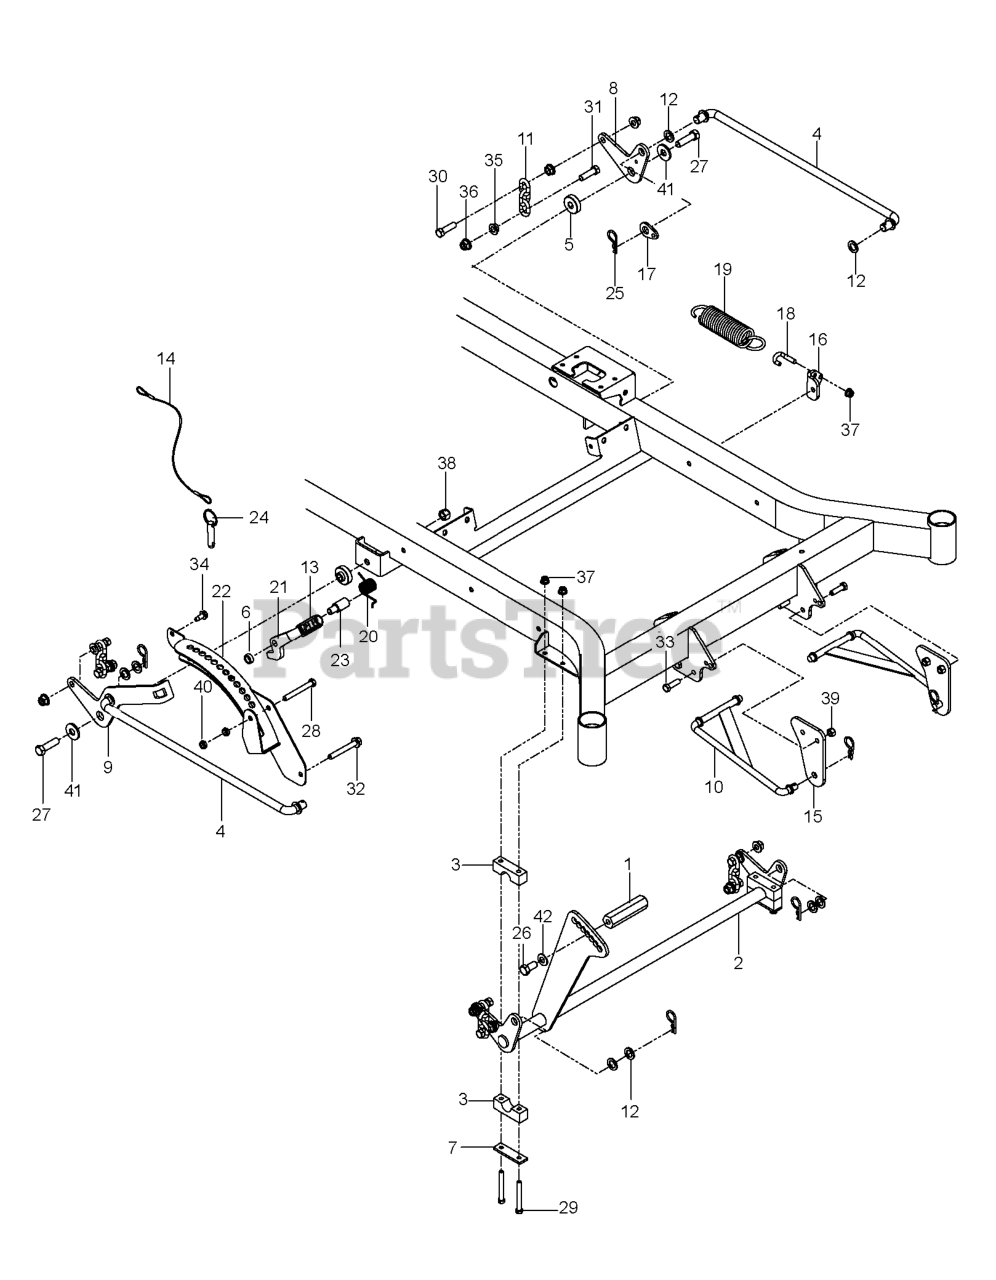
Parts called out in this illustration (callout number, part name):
1	PEDAL, FOOT, HEX
2	SHAFT, FT, LIFT - BLK
3	PILLOW BLOCK
4	CROSS LINK
5	IDLER SPACER
6	SPACER, .3
7	REINFORCEMENT BAR
8	BELLCRANK, RR, LIFT
9	BELLCRANK, RR, RT
10	STRUT LINKAGE
11	LIFT CHAIN - 3 LINK
13	GRIP, TRANSPORT-RELEASE
15	MOUNT, STRUT
16	MOUNT, SPRING
17	TAB, SPRING
20	SPRING, TORSION
21	LATCH, TRANSPORT
22	HEIGHT, ADJUST, DECK
23	PIVOT, LATCH, TRANSPORT
24	PIN, 1/2 X 1 1/2, DETENT RING
25	PIN, COTTER 1 3/4
26	HHCS 1/2-13 X 1
27	HCS 1/2-13 X 1 3/4 GR 8
28	HCS 3/8C X 3
29	HCS 5/16C X 2-3/4
30	HCS 7/16C X 1 1/2
31	HCS 7/16 - 14 X 1 3/4
32	HHFS 3/8-16 X 2 3/4
33	HCS 3/8C X 1 1/4 GR5
34	BOLT 5/16-18 X 3/4
35	NUT 7/16C WHIZ
36	NUT 7/16-14 HEX WHIZ LK
37	5/16-18 NYLOC FLANGE NUT
38	NUT 1/2-13 HEX NYLOC ZD
39	NUT 3/8-16 NYLOC
40	NUT HEX 3/8-16 NYLON, THIN
41	WASH USS FLAT 1/2
42	WASHER, 7/16 DISC SPRING
